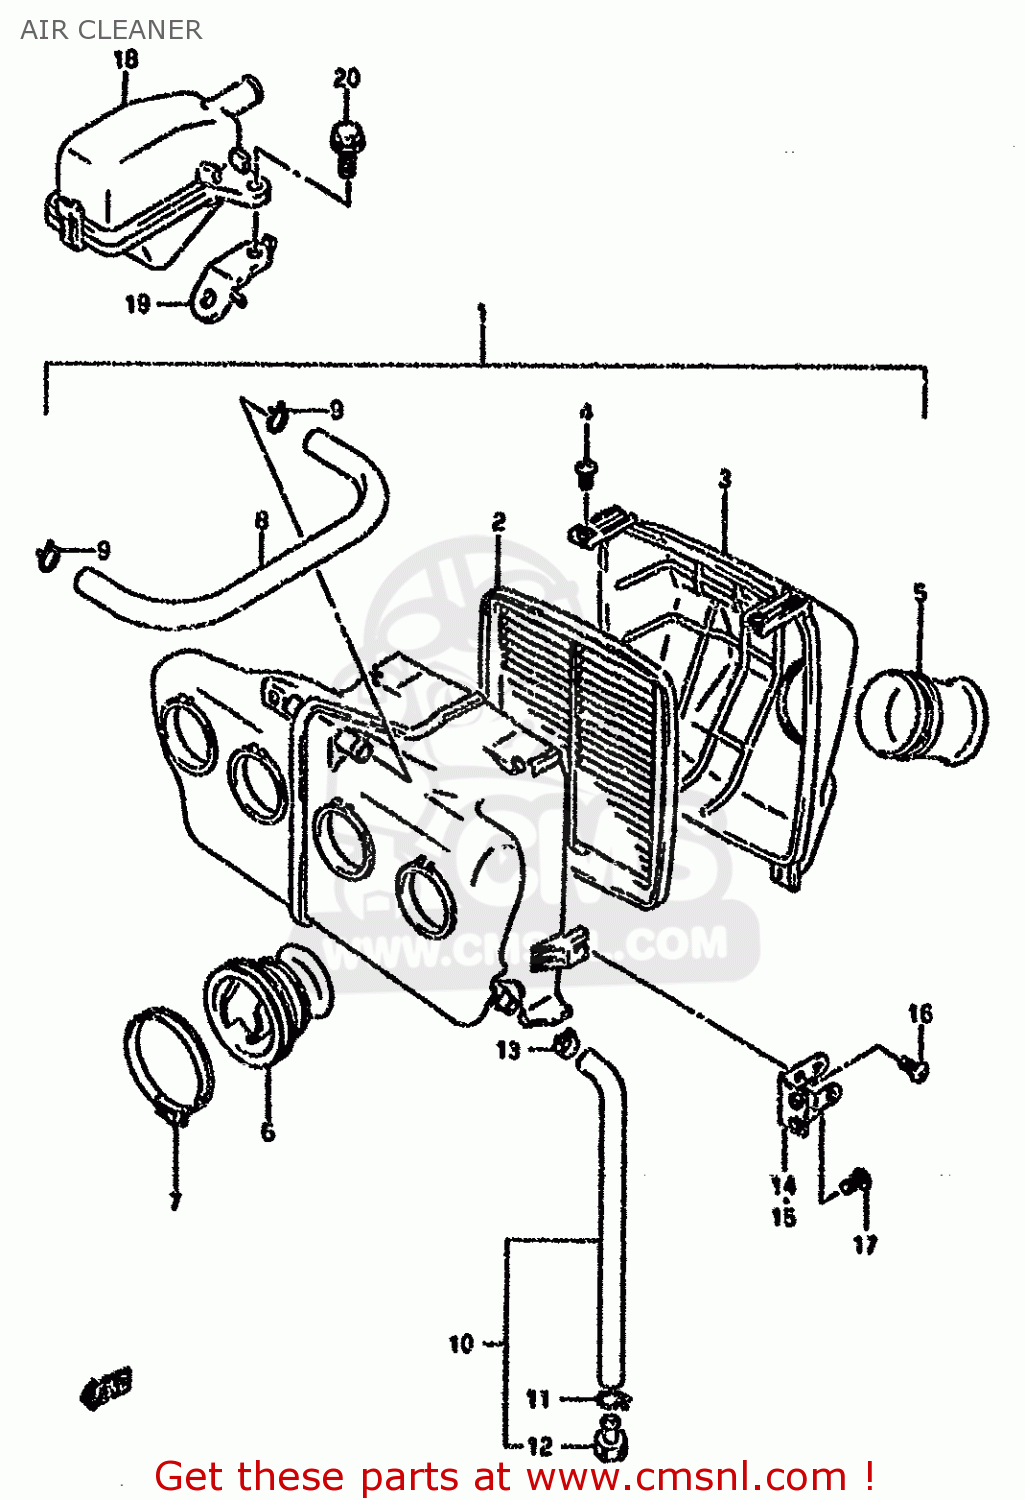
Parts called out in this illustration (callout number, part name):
1	CLEANER ASSEMBLY,AIR
2	FILTER,AIR
3	CAP,AIR CLEANER
4	SCREW 5X12
5	TUBE,INLET
6	TUBE,OUTLET
7	CLAMP
8	TUBE,BREATHER
9	CLIP
10	TUBE,DRAIN
11	CLIP
12	STOPPER,DRAIN
13	CLIP
14	BRACKET COMP,AIR CLEANER
15	BRACKET COMP,AIR CLEANER
16	SCREW
17	SCREW
18	CLEANER ASSY,AIR NO.2
19	BRACKET,AIR CLEANER NO.2
20	BOLT
